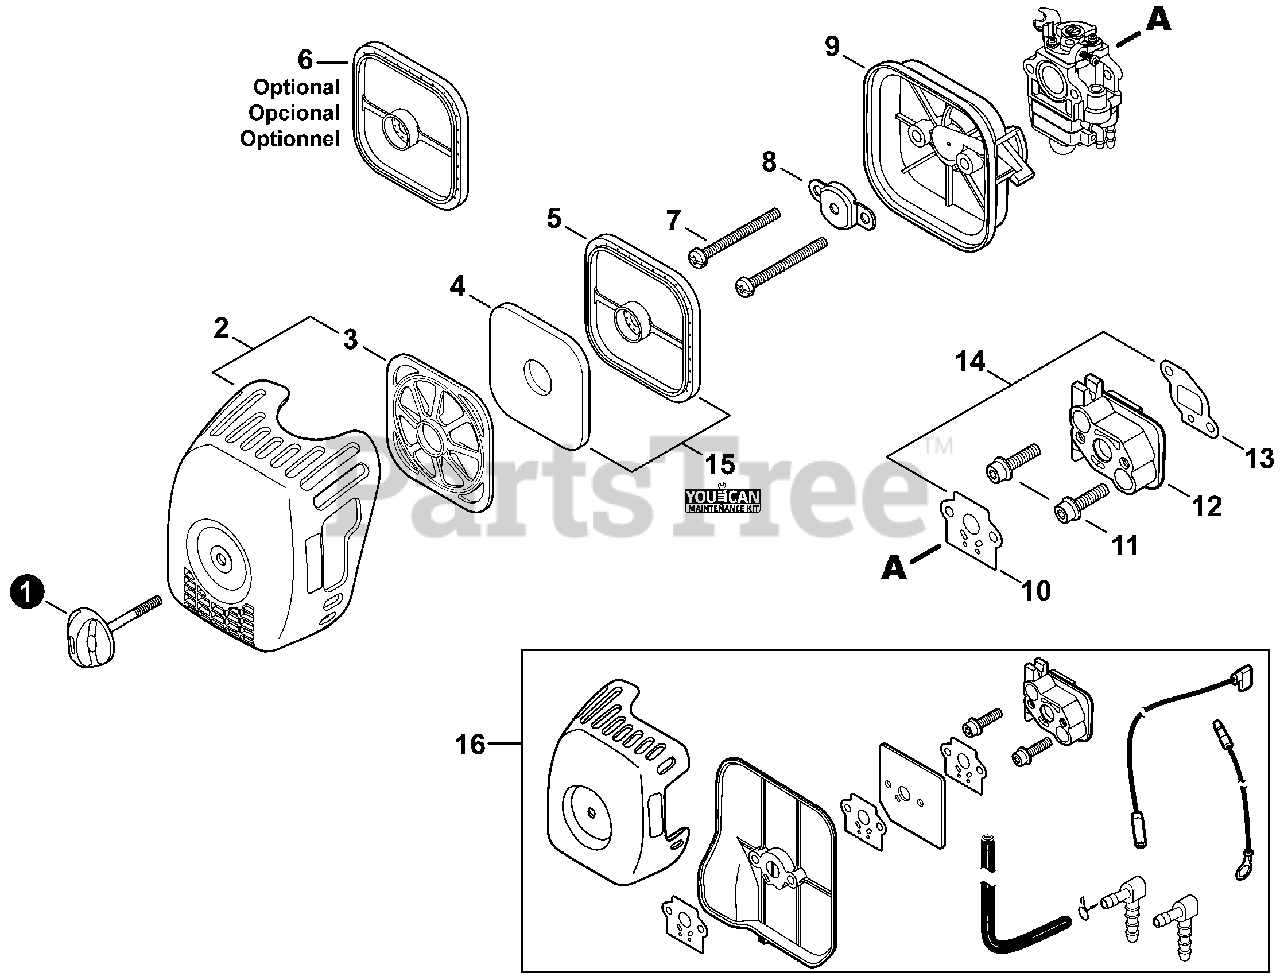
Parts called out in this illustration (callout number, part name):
1	THUMBSCREW
2	COVER KIT, AIR FILTER
3	RETAINER, PRE-FILTER
4	PRE-FILTER, FOAM
5	FILTER, AIR - DOUBLE LAYER
6	FILTER, AIR - SINGLE LAYER
7	SCREW 5×60
8	PLATE, PREVENT
9	CASE, AIR FILTER
10	GASKET, INTAKE
11	BOLT 5×30
12	INSULATOR, INTAKE
13	GASKET, INTAKE
14	GASKET KIT
15	TUNE-UP KIT - YOUCANT
16	HOT START KIT 280
